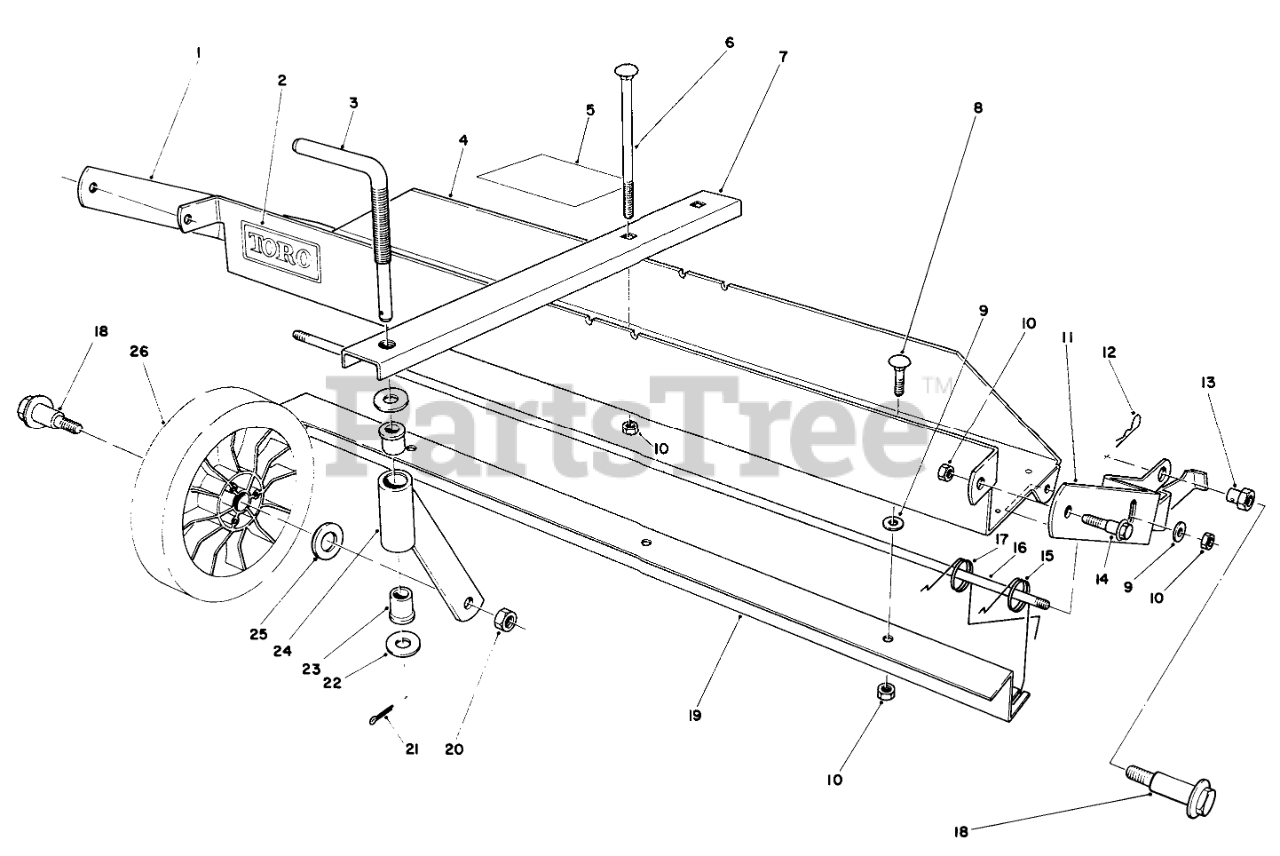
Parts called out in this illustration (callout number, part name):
1	Frame R.H.
2	Decal-Toro
3	CASTOR ADJ ROD
4	Frame-Main (Incl. Ref. #2)
5	Decal-Instruction
6	SCREW-CARR
7	Castor Frame
8	BOLT-CARR
9	WASHER-FLAT
10	NUT-HEX, SIDE DEFORM
11	LH MTG FRAME
12	PIN-COTTER, HAIR
13	PIVOT NUT
14	SCREW-SHOULDER
15	DETHATCHER SPRING
16	SPRING SUPPORT ROD
17	DETHATCHER SPRING
18	BOLT-WHEEL
19	SPRING GUIDE STRAP
20	Nut
21	PIN-COTTER
22	Washer
23	FLANGE BUSHING
24	Castor Tube & Support
25	WASHER
26	Wheel Assembly
